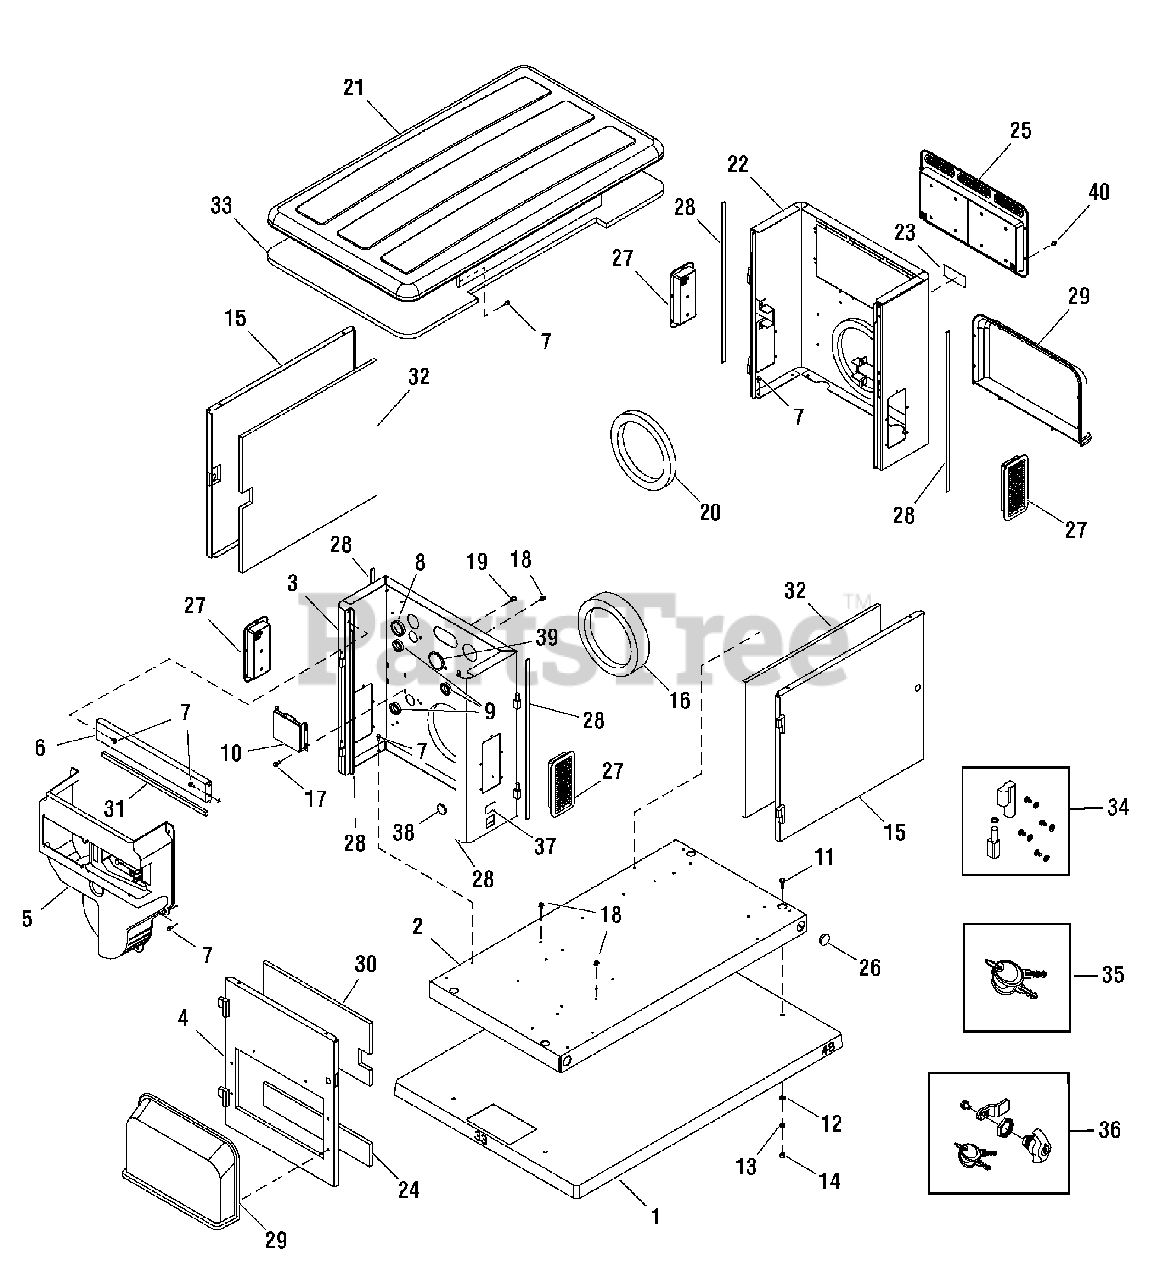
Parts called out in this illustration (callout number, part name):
3	BULKHEAD ASSEMBLY, Engine
6	SUPPORT RAIL ASSEMBLY
7	BOLT
10	REGULATOR, Voltage
11	*CAPSCREW, Hex Head, 3/8-16 x 1
12	*WASHER, Flat, 3/8 - M10
13	*WASHER, Lock, 3/8
14	*NUT, 3/8-16
16	SEAL, Foam
20	SEAL, Foam
22	BULKHEAD ASSEMBLY, Alternator
29	COVER, Air Intake
